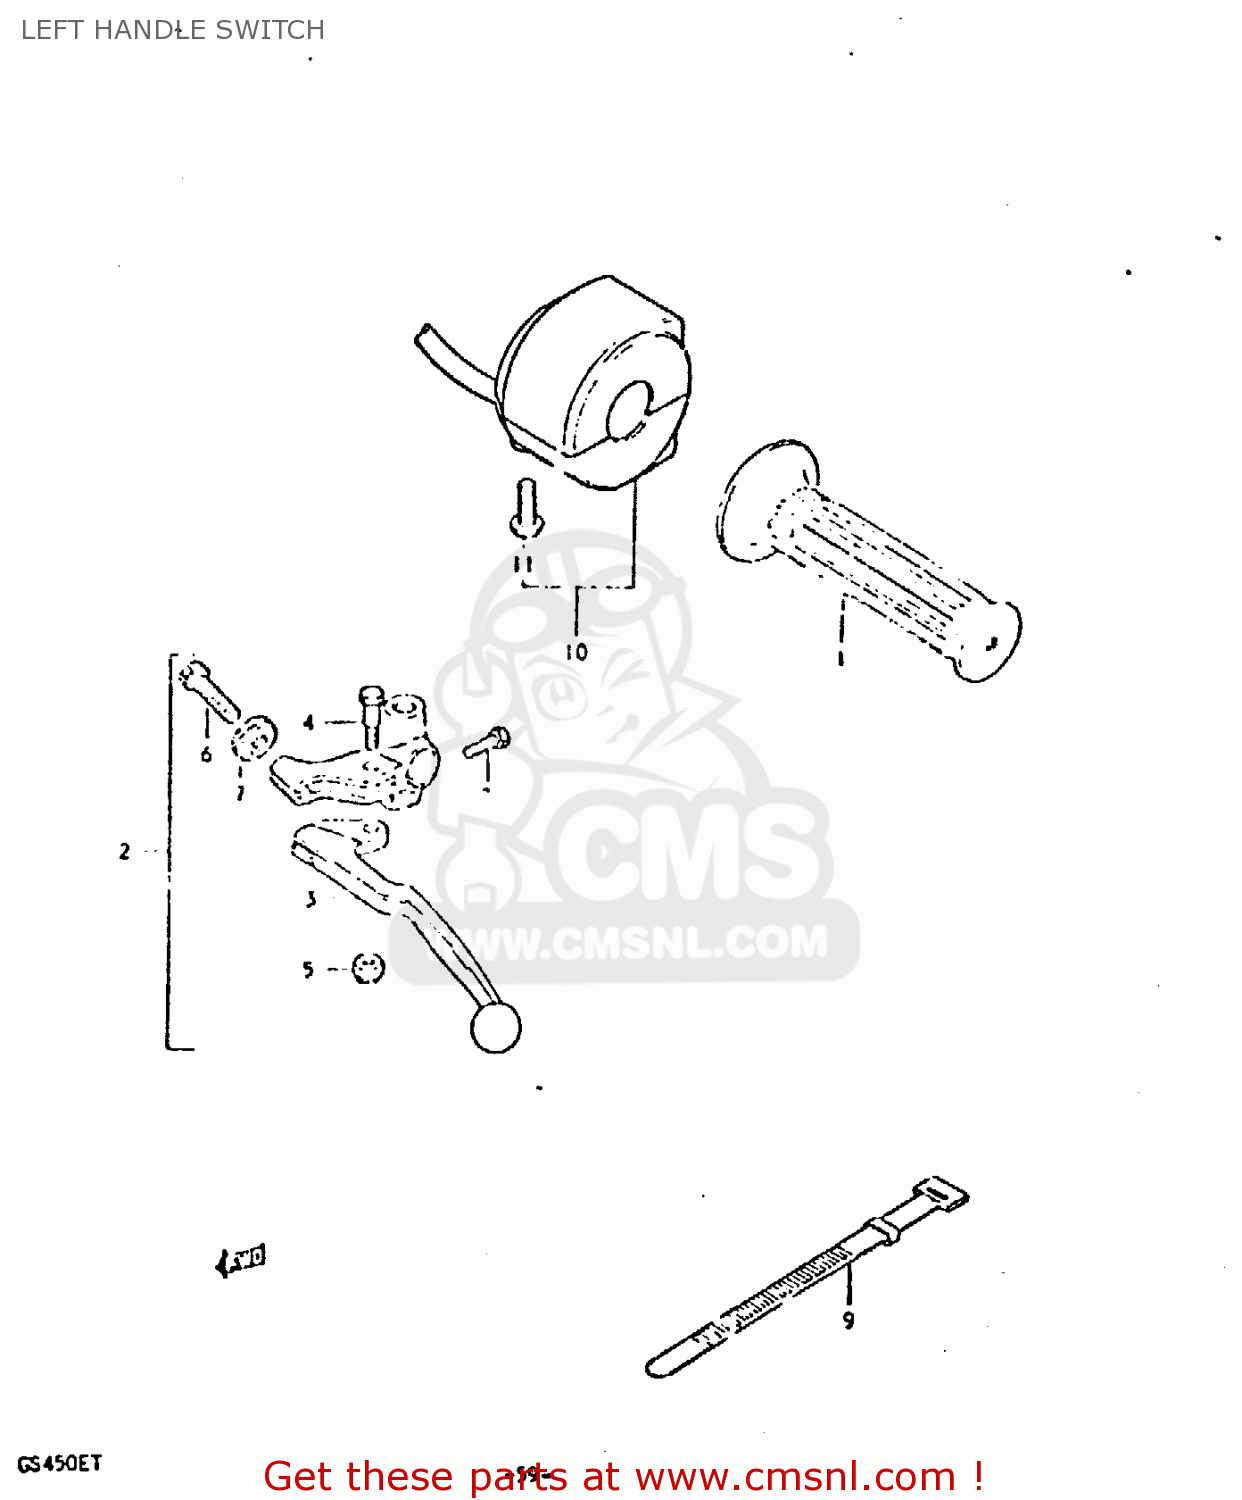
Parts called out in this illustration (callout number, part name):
1	GRIP,LEFT
2	LEVER ASSY, CLUTCH
3	LEVER,CLUTCH
4	BOLT,LEVER
5	NUT 6MM
6	ADJUSTER,CABLE
7	NUT,CABLE ADJUSTER
8	BOLT
9	CLAMP(L:120)
10	SWITCH ASSY, HANDLE LH
11	SCREW
